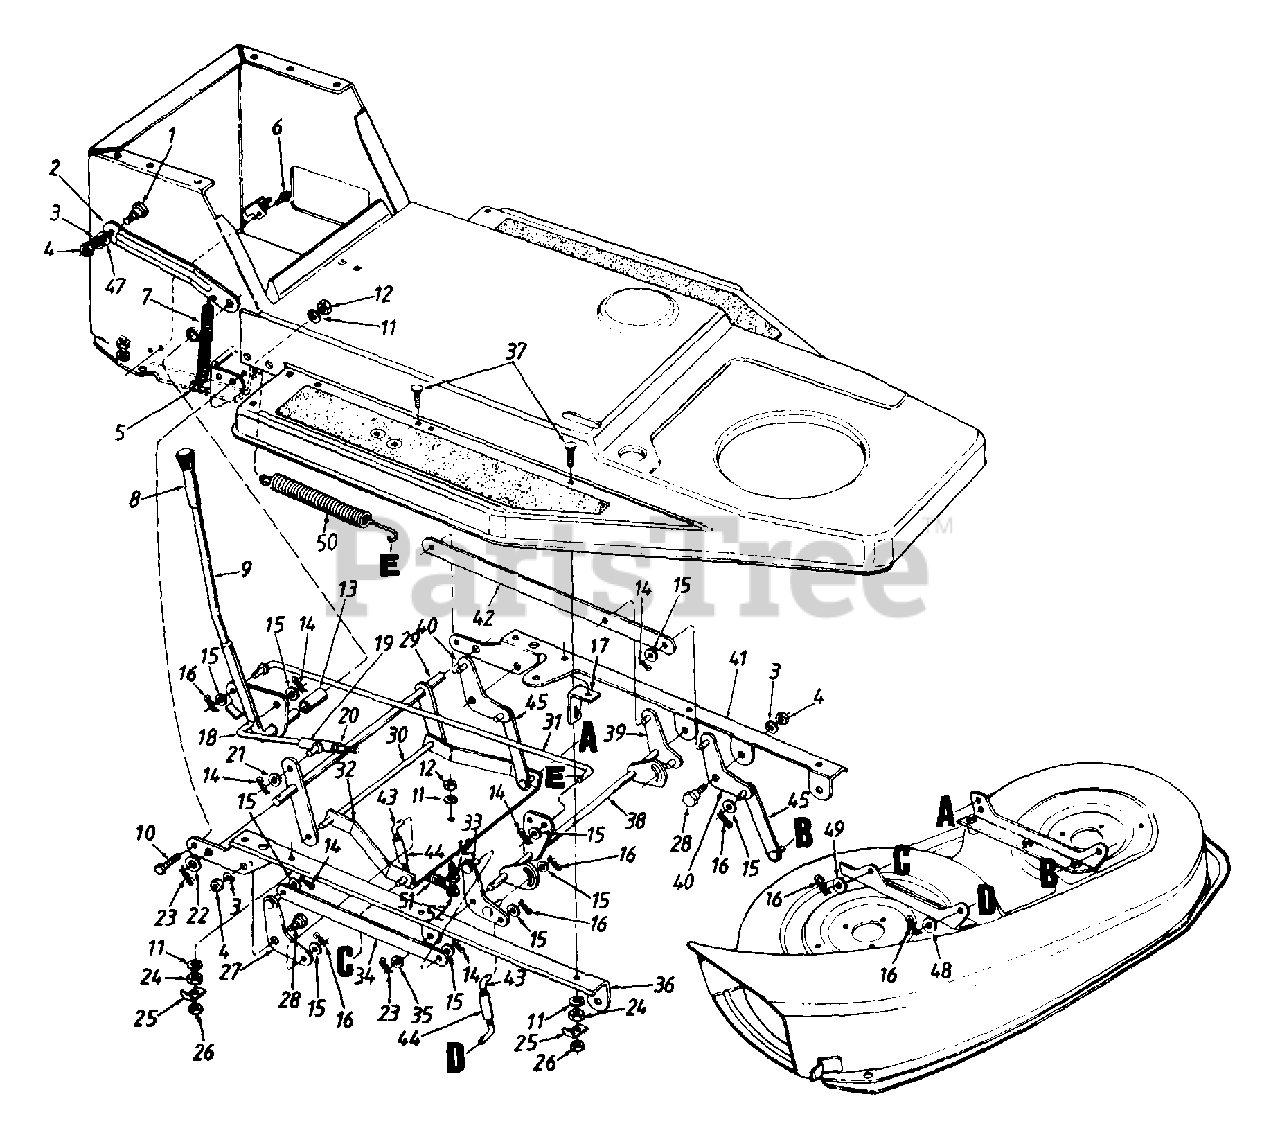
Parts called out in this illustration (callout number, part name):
1	Shld. Bolt .5" Dia. x .34" Lg.
2	Lift Handle Support Strap
3	L-Wash. 3/8" I.D.
4	Hex Nut 3/8-16 Thd.
5	Hex Bolt 1/4-28 x 1.25" Lg.
6	Hex Wash. Hd. TT-Tap Scr. 1/4-20 x .5" Lg.
7	Ext. Spring
9	Deck Lift Handle Ass'y.
10	Hex Wash. TT-Tap Scr. 5/16-18 x .62" Lg.
11	L-Wash. 5/16" I.D.
12	Hex Nut 5/16-18 Thd.
13	Spacer 5/8" I.D. x .78"
14	Cot-Pin 3/32" Dia. x .75" Lg.
15	Fl-Wash..406" I.D. x .75" O.D.
16	Internal Cot-Pin 5/16" Dia.
19	Pivot Sleeve Ass'y.
20	Hex L-Nut 3/8-16 Thd.
21	Thrust Washer .382" I.D.
22	Fl-Wash..635" I.D. x .93" O.D.
23	Cot-Pin 1/8 Dia. x 1.25" Lg.
24	Hex Nut 5/16-24 Thd.
25	Harness Retainer
26	Hex Cent. L-Nut 5/16-24 Thd.
27	Deck Pivot Brkt. Ass'y.- R.H. Rear
28	Shld. Bolt .625" Dia. x .170" Lg.
29	Deck Link Shaft Ass'y.
30	Shaft 11.2" Lg.
31	Deck Lift Rod
32	Deck Stabilizer Brkt.
35	Fl-Wash. 5/8" I.D. x 1.0" O.D.
36	Pivot Support Brkt. - R.H.
37	Rib Neck Bolt 5/16-24 x .84" Lg.
38	Cross Shaft Ass'y.
39	Deck Pivot Brkt. Ass'y. - L.H.
40	Deck Pivot Brkt. Ass'y. - L.H.
41	Pivot Support Brkt. - L.H.
42	Connecting Link - L.H.
43	Lift Link 3/8-24 x 1.25" Lg.
44	Adj. Lift Link Ass'y.
45	Deck Lift Link Ass'y.
47	Fl-Wash..531" I.D. x .94"
48	Fl-Wash..406" I.D. x .75"
49	Fl-Wash. 3/8" I.D.
50	Ext. Spring .87" Dia.
51	Ext. Spring 11" Lg.
52	Hex Bolt 5/16-18 x 7/8" Lg.
